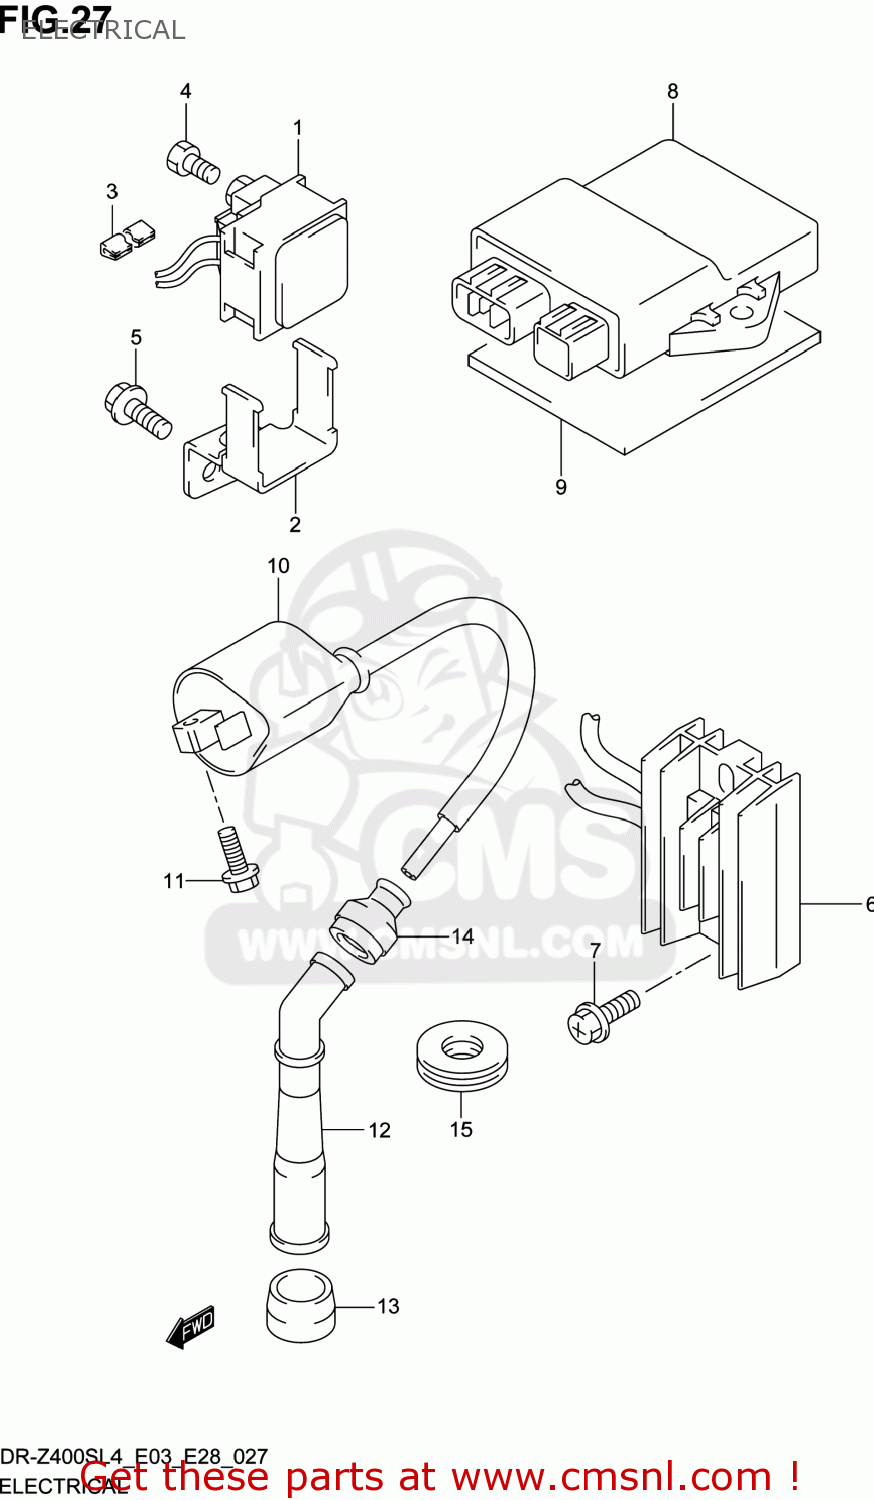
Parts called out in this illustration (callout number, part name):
1	RELAY ASSY,STARTING MOTOR
2	BRACKET,STARTING MOTOR RELAY
3	PROTECTOR,STARTING MOTOR LEAD
4	SCREW(6X8)
5	BOLT
6	RECTIFIER ASSY
7	SCREW
8	CDI UNIT
9	CUSHION(30X50X3)
10	COIL ASSY,IGNITION
11	BOLT
12	CAP,SPARK PLUG
13	SEAL,SPARK PLUG
14	SEAL,HIGH TENSION CORD
15	COVER,SPARK PLUG CAP
